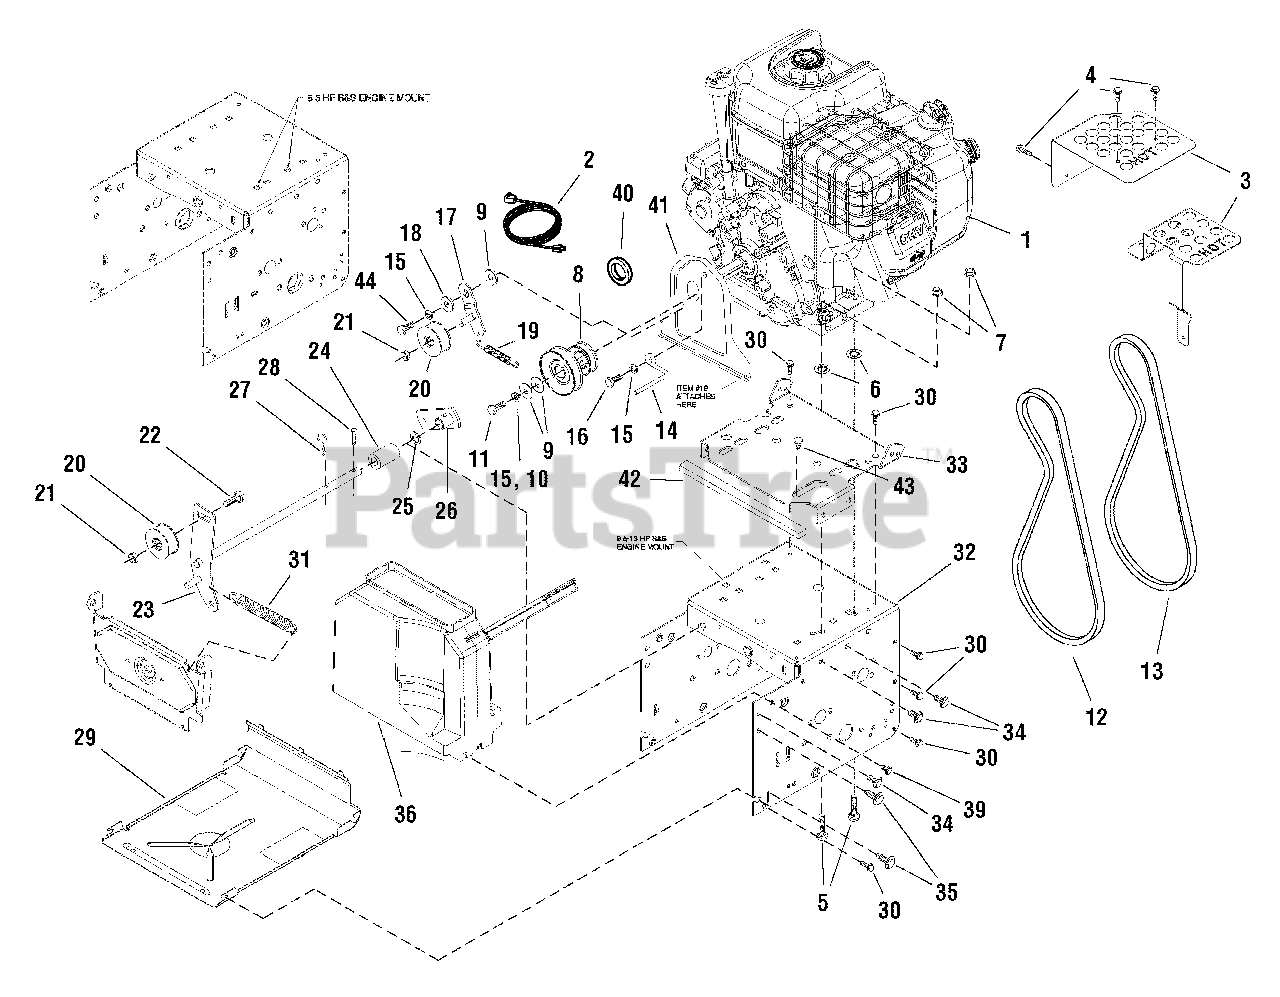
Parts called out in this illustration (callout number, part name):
1	* ENGINE, 8.5HP B&S Mod. #15C1140112E1
1	* ENGINE, 9.5HP B&S Mod. #20A4140117E1
1	* ENGINE, 10.5HP B&S Mod. #20E2140118E1
1	* ENGINE, 11.5HP B&S Mod. #21C2140132E1
1	* ENGINE, 8.5HP B&S Mod. #15C1140111E1
1	* ENGINE, 9.5HP B&S Mod. #20A4140119E1
1	* ENGINE, 10.5HP B&S Mod. #20E2140113E1
1	* ENGINE, 11.5HP B&S Mod. #21C2140115E1
2	CORD, Electric Start
3	GUARD, Muffler
4	SCREW, Hex Washer Head Taptite
5	CARRIAGE BOLT, 5/16-18 x 1-1/2
6	NUT, Speed
7	NUT, Hex Flange 5/16-18 Whiz Lock
7	NUT, Hex Flange 5/16-18 ESNA
8	PULLEY, Engine
9	WASHER, 3/8
9	WASHER, 5/16-1
10	LOCKWASHER, Spring 3/8
11	CAPSCREW, Hex Head 3/8-24 x 1-1/4 G8
11	CAPSCREW, Hex Head 3/16-24 x 1-1/4 G8
12	V-BELT, 3L 33.13, Drive
13	V-BELT, 4L 38.50, Auger
13	V-BELT, 4L 36.50, Auger
14	STOP, Belt
15	LOCKWASHER, Spring 5/16
16	CAPSCREW, Hex Head 5/16-24 x 3/4 G5
17	IDLER BRACKET ASSEMBLY, Drive Belt
18	BUSHING, Idler Bracket
19	SPRING, Extension Idler
20	IDLER, Plastic Ball Bearing
21	NUT, Hex Centerlock Jam 3/8-16
22	CARRIAGE BOLT, 3/8-16 x 1-1/4
23	IDLER, Auger
24	SPACER/AUGER BRACKET
25	WASHER, 1/2
26	BRACKET & HUB ASSEMBLY, Spring
27	PIN, Hair
28	PIN, Clevis
29	PANEL, Bottom
30	SCREW, Hex Washer Head Taptite 1/4-20 x 5/8
31	SPRING, Extension Auger Idler
32	FRAME, EZ Turn Axle
33	PLATE, Engine Mount
34	SCREW, Hex Washer Head Taptite 5/16-18 x 1/2
35	SCREW, Hex Washer Head Taptite 5/16-18 x 3/4
36	COVER, Belt w/Toolbox B&S
39	SCREW, 1/4-AB x 3/4 Hex
40	SHAFT, Seal
41	SEAL, Plate
42	SEAL, Strip
43	CLIP, Pine Tree
44	CAPSCREW, Hex Head 5/16-24 x 1 G8
